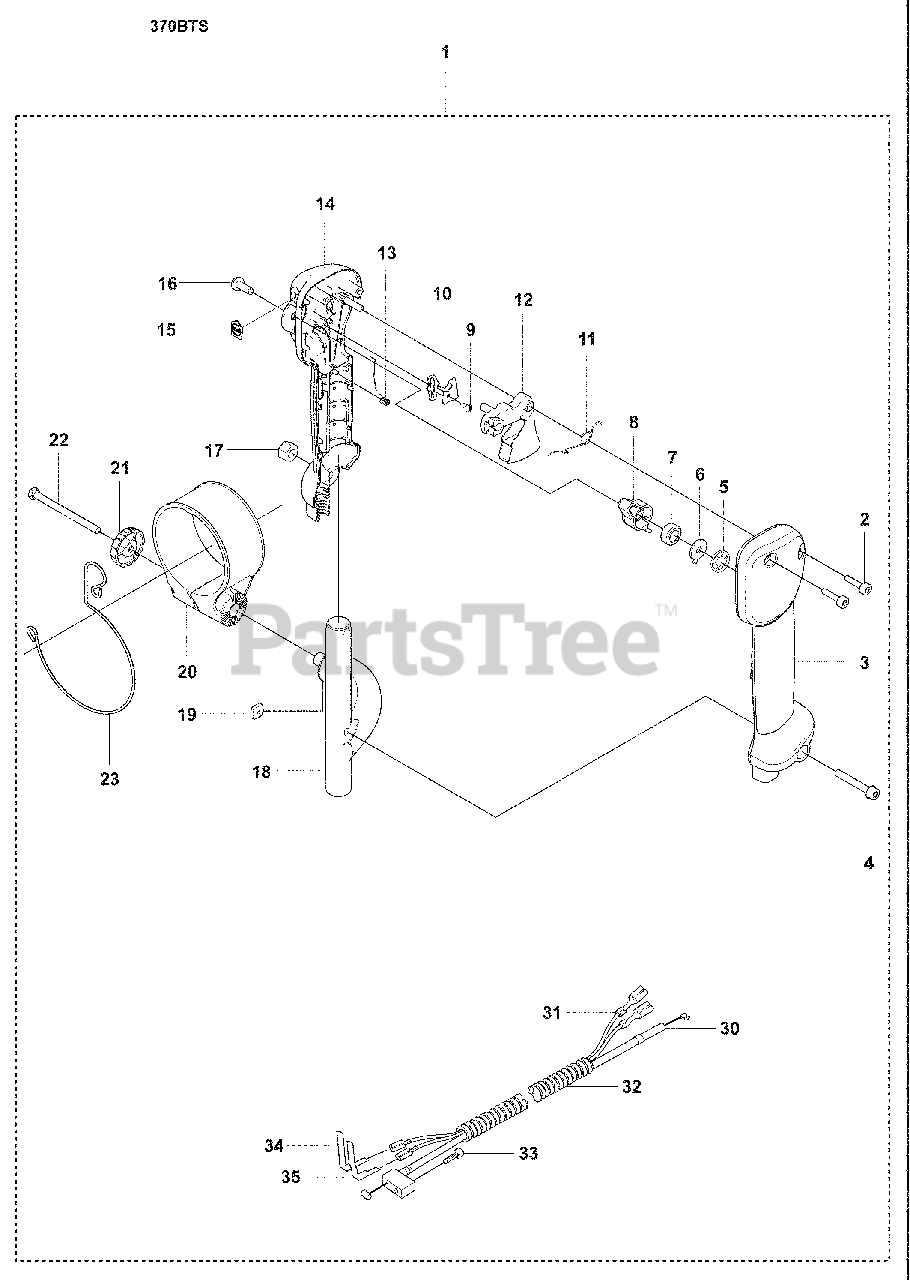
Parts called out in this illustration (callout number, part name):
1	HANDLE ASSY 170BT
3	Right Half Handle
4	Screw, Ihscfm M5 X 35 10.9 ZP
7	Spring, Rubber
8	Stop Lever
14	Left Half Handle
16	Pivot Shaft
19	Square Nut
20	HOLDER TH
21	Air Filter Cover Knob
30	Cable, Complete
31	Cord
34	Contact Spring
35	Contact Spring
